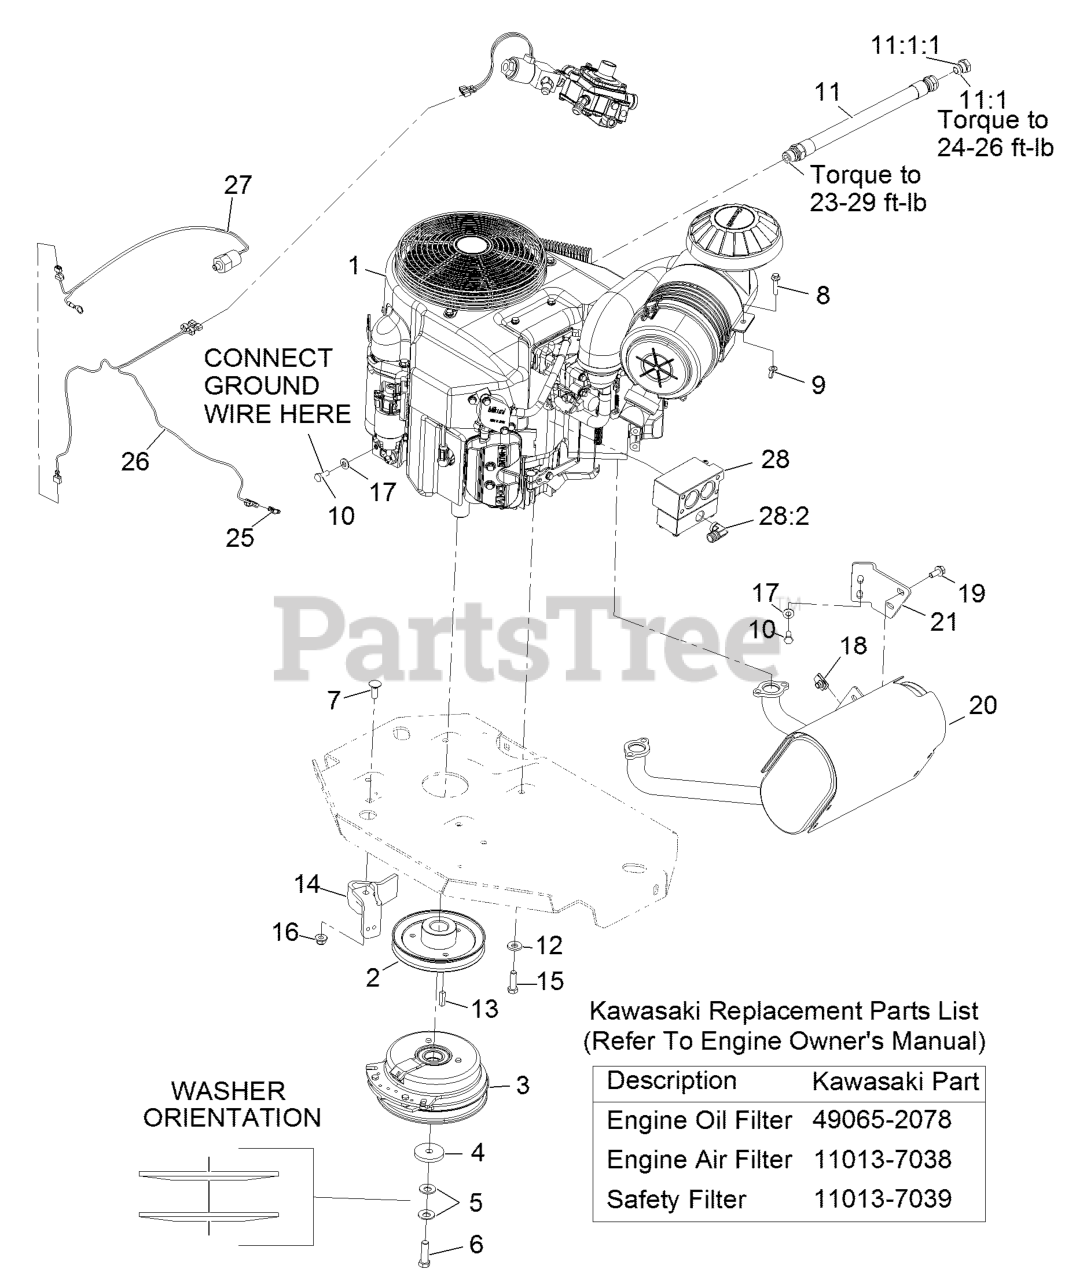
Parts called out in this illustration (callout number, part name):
2	SHEAVE
3	CLUTCH KIT
4	WASHER-CLUTCH
5	WASHER-SPRING
6	SCREW-HH 7/16-20 X 1 1/2 W/LOCTITE
7	SCREW-CARR
8	SCREW-HHF
9	NUT-WING
10	SCREW-HH
11	ENGINE OIL DRAIN HOSE ASM
11:1	PLUG-HH
11:1:1	O-RING
12	WASHER-BELLEVILLE
14	CLUTCH-ANCHOR
15	SCREW-HH
16	NUT-HF, NI
17	WASHER-SPRING
19	SCREW-HHF
20	MUFFLER
21	BRACKET-MUFFLER
25	TERMINAL-TAB
26	WIRE HARNESS
28	LPG MIXER ASM
